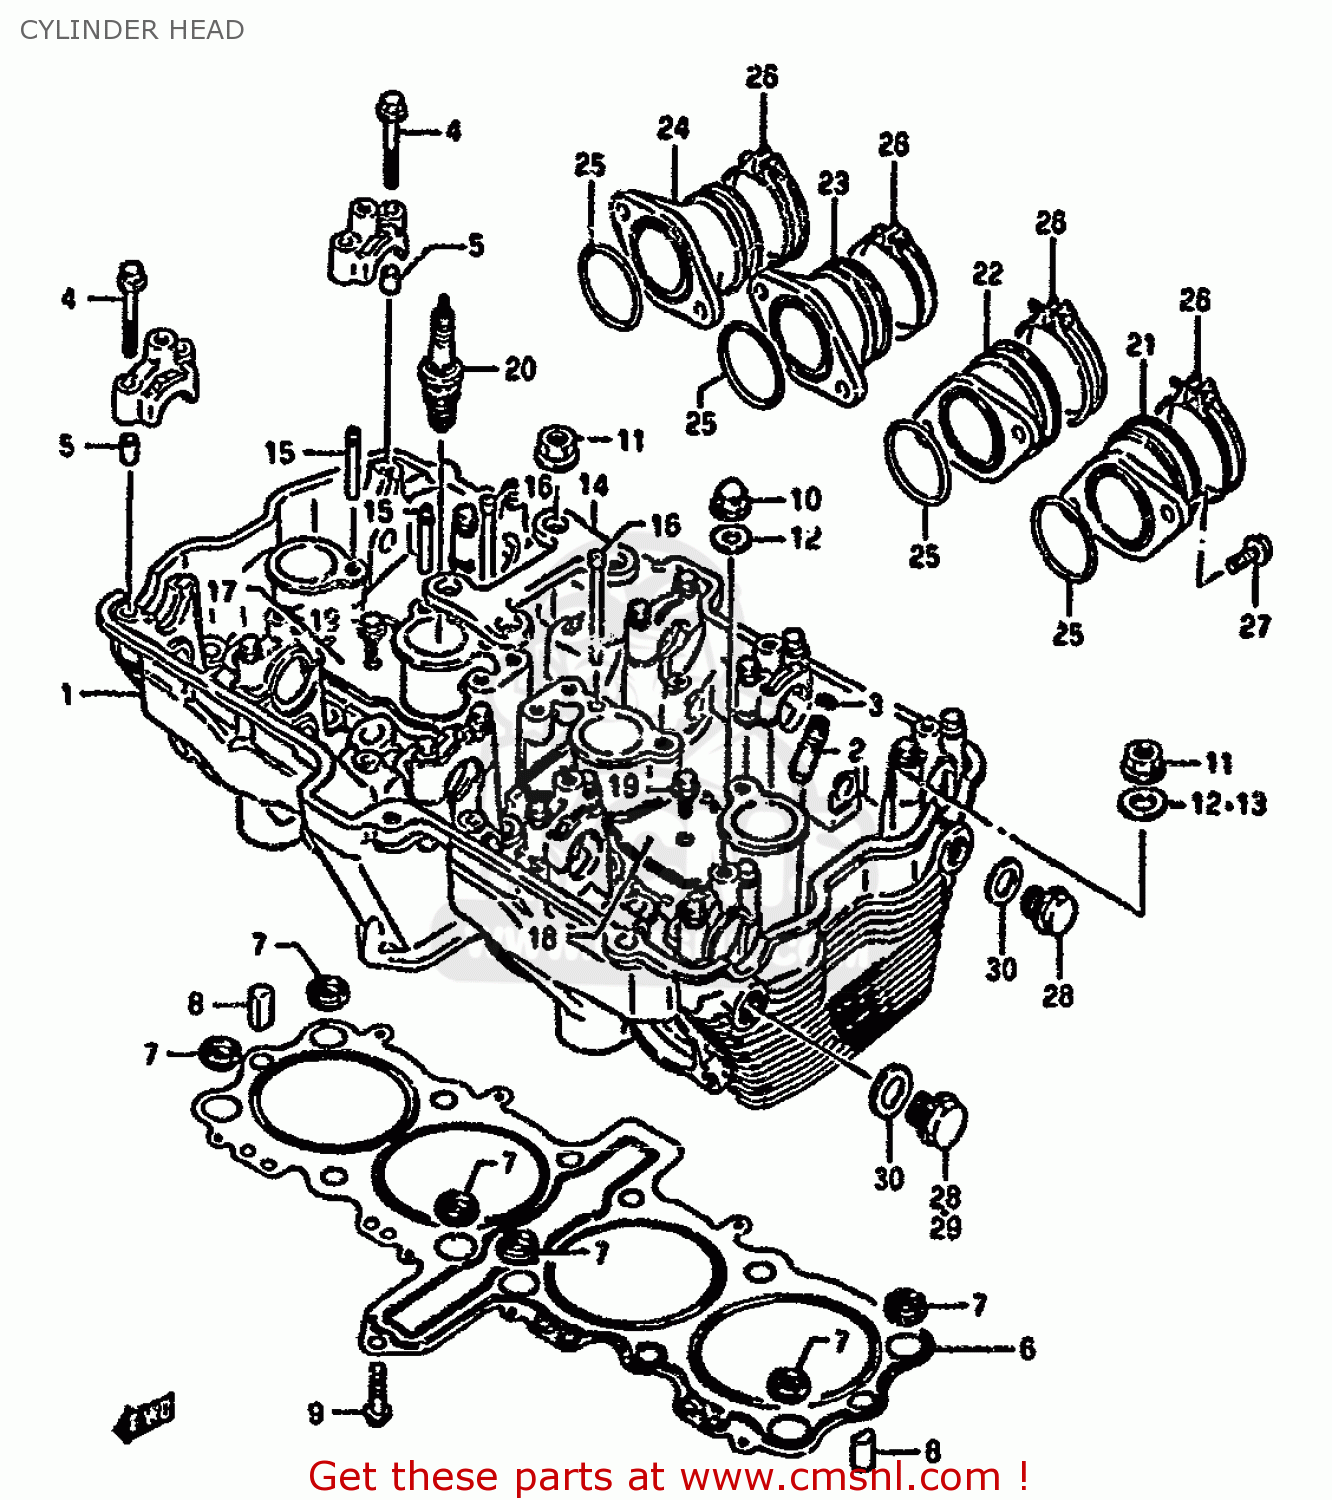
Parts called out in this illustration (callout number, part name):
1	HEAD ASSEMBLY,CYLINDER
2	GUIDE,VALVE
3	RING,SNAP
4	BOLT(6X39)
5	PIN(6.2X8X11)
6	GASKET,CYLINDER HEAD (NAS)
7	O-RING,HEAD GASKET
8	PIN
9	BOLT
10	NUT
11	NUT
12	GASKET(10.2X20X2).3 (NAS)
13	WASHER (10.5X22X2.3)
14	PLATE,HEAD REINF
15	PIPE,OIL NO.1
16	PIPE,OIL NO.3
17	PLATE,OIL PIPE,R
18	PLATE,OIL PIPE,L
19	BOLT
20	PLUG,SPARK(JR9B)
21	PIPE,INTAKE NO.1
22	PIPE,INTAKE NO.2
23	PIPE,INTAKE NO.3
24	PIPE,INTAKE NO.4
25	O RING(D:2.4,ID:39.7)
26	CLAMP
27	SCREW
28	PLUG
29	PLUG
30	GASKET(14X19.2X2) (NAS)
